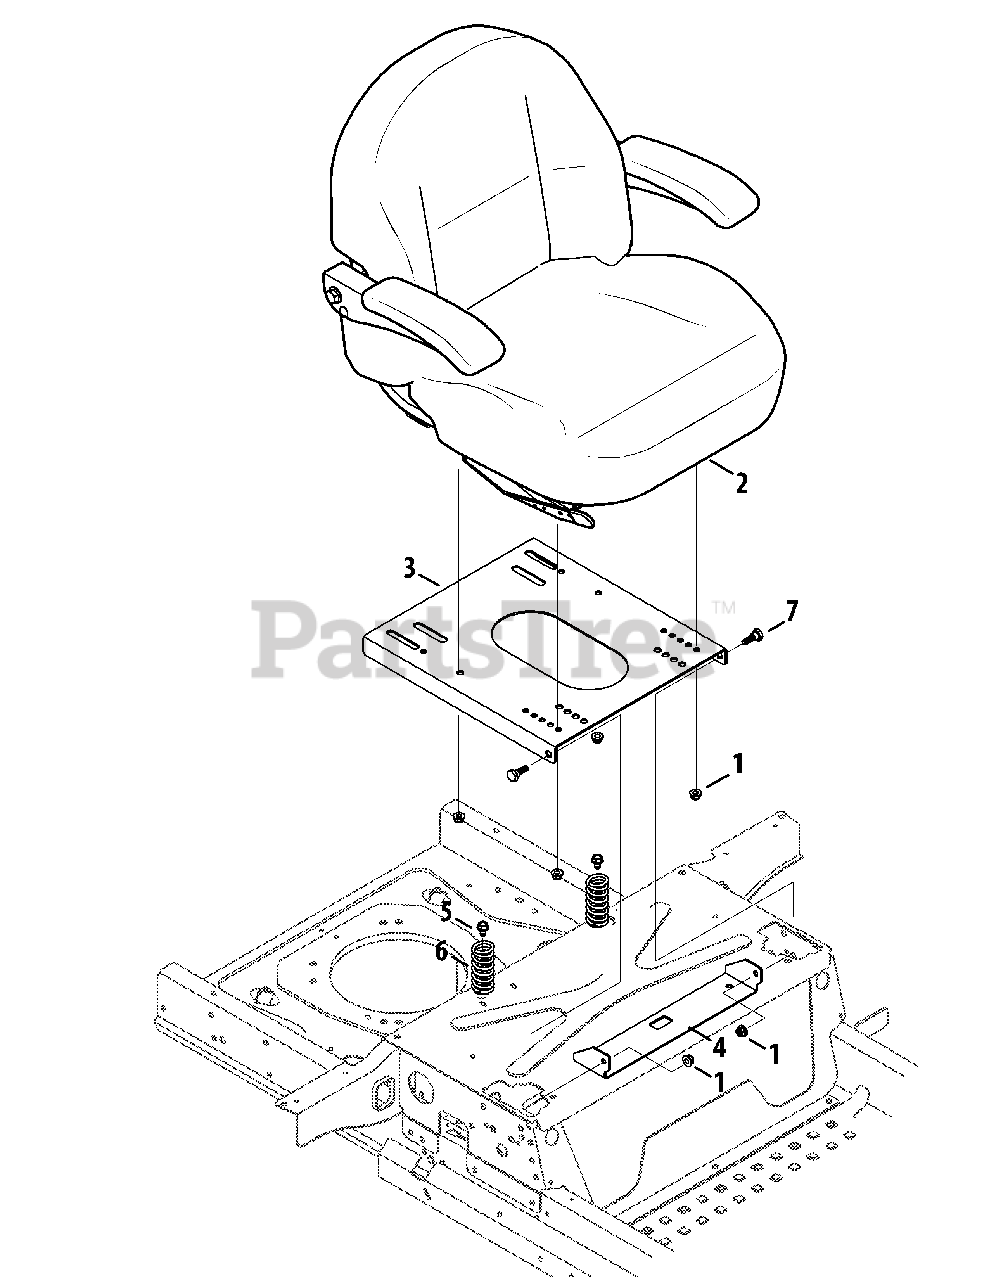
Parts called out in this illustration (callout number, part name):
1	Flange Lock Nut, 5/16-18
3	Seat Plate
5	Hex Washer Screw, 5/16-18 x .750
6	Compression Spring, 1.28 x 3.125
7	Shoulder Screw, 5/16-18 x .437 x .268
